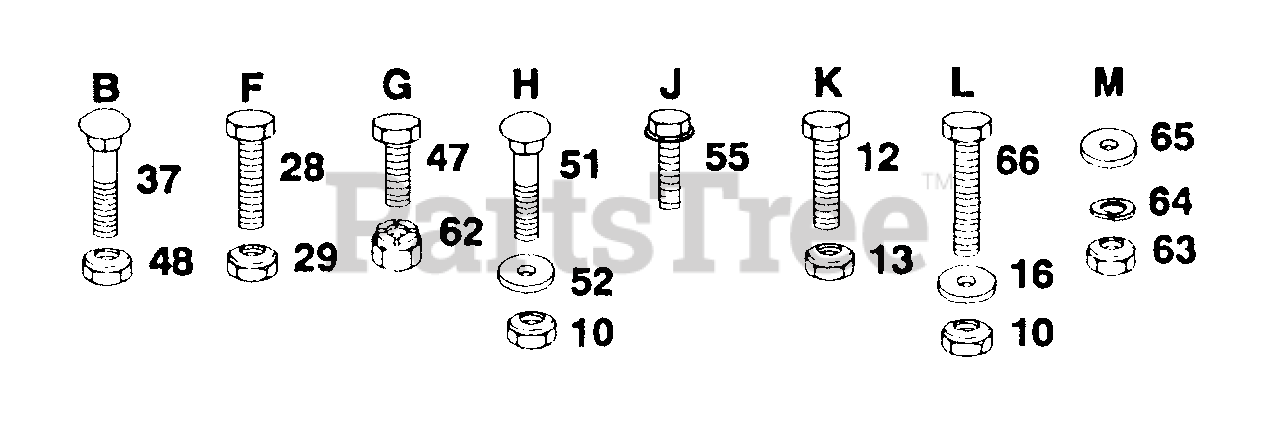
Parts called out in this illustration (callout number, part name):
10	Locknut 5/16-18
12	Bolt, Hex 1/4-20 x 1/2
13	Locknut 1/4-20
16	Washer 11/32 x 3/4 x 16 Gauge
28	Bolt, Shoulder
29	Nut, Hex Flange 1/4-20
37	Bolt, Hex 3/8-16 x 1
47	Bolt, Carriage 3/8-16 x 3/4
48	Locknut 3/8-16
51	Bolt, Carriage 5/16-18 x 1
52	Washer 11/32 x 1 x 10 Gauge
55	Screw, Hex Wsh. Thdrol 3/8-16 x 1/2
62	Nut, Centerlock 3/8-16
63	Nut, Hex 1/4-20
64	Washer, Lock 1/4
65	Washer 9/32 x 3/4 x 16 Gauge
66	Bolt, Hex 5/16-18 x 3/4
